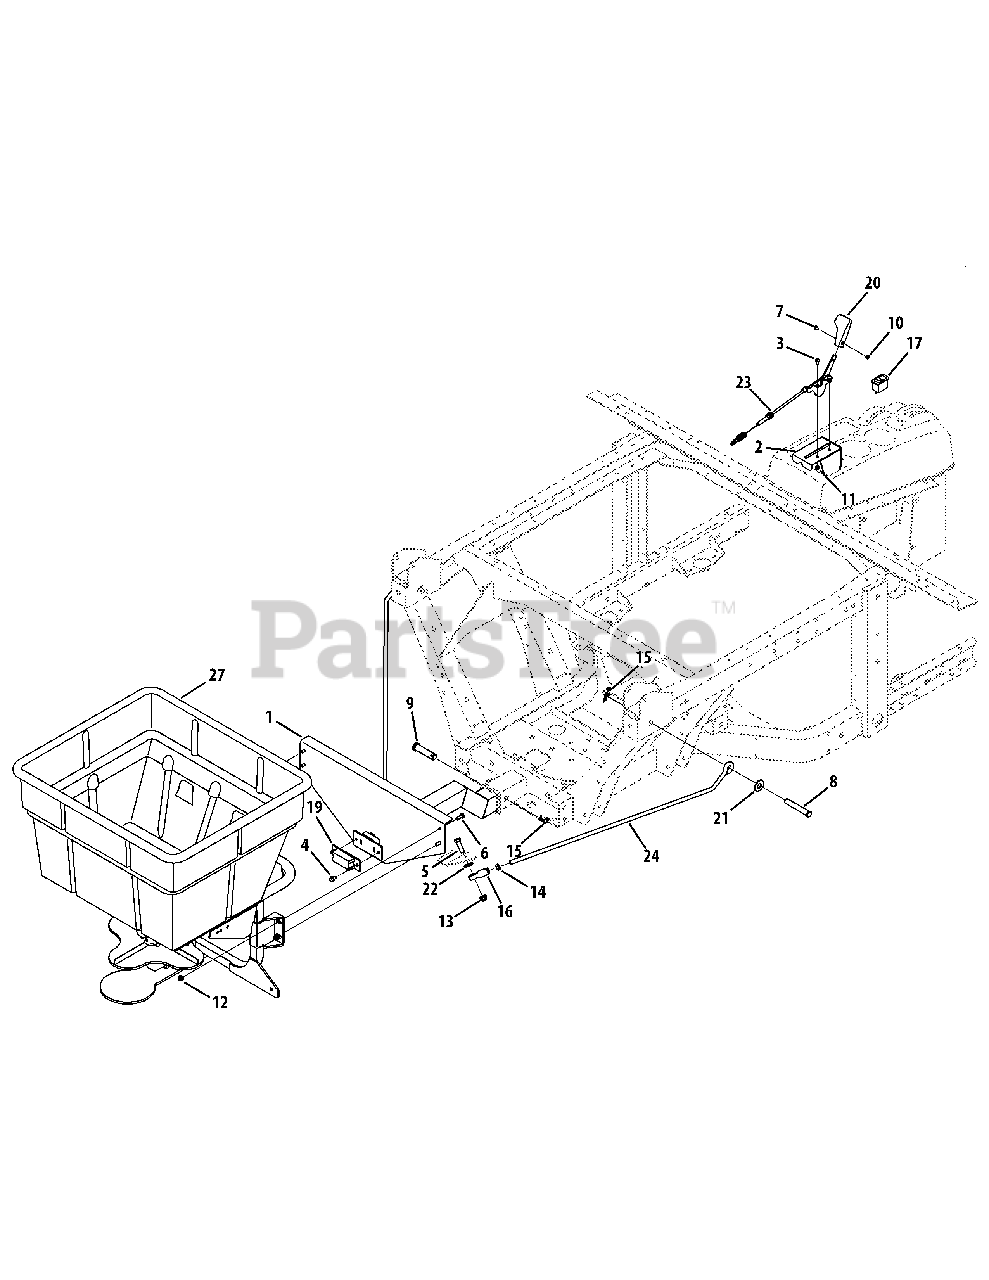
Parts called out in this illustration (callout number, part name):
1	Brkt. Assy., Spreader Mount, UV
2	Brkt. Assy., Cable Mount
3	Scr., Mach., #10-24 x .500
4	Scr., tt, 1/4-20 x .625
5	Hhcs, 3/8-16 x 1.25
6	Hhcs, 1/4-20 x .75
7	Scr., Mach., #8-32 x .375
8	Pin, Clevis, .50 x 3.25
9	Pin, Clevis, .625 x 2.313
10	Nut, Hex, #8-32
11	Nut, Hexlk, #10-24
12	Nut, Flglk., 1/4-20
13	Nut, Flglk., 3/8-16
14	Nut, Jam, 3/8-24
15	Pin, Click, .092 x 1.64 Lg.
16	Rod, End, 3/8 ID
17	Switch, Rocker, On/Off
19	Bmpr., Suspn., Extn.
20	Knob, Throttle Control
21	Wash., Flat, 1/2 x 1.25 x .10
22	Wash., Flat, .38 x .93 x .110
23	Cbl., Cont., On/Off, Spreader, UV
24	Link, Tie Rod, Spreader, UV
27	Spreader Assembly
